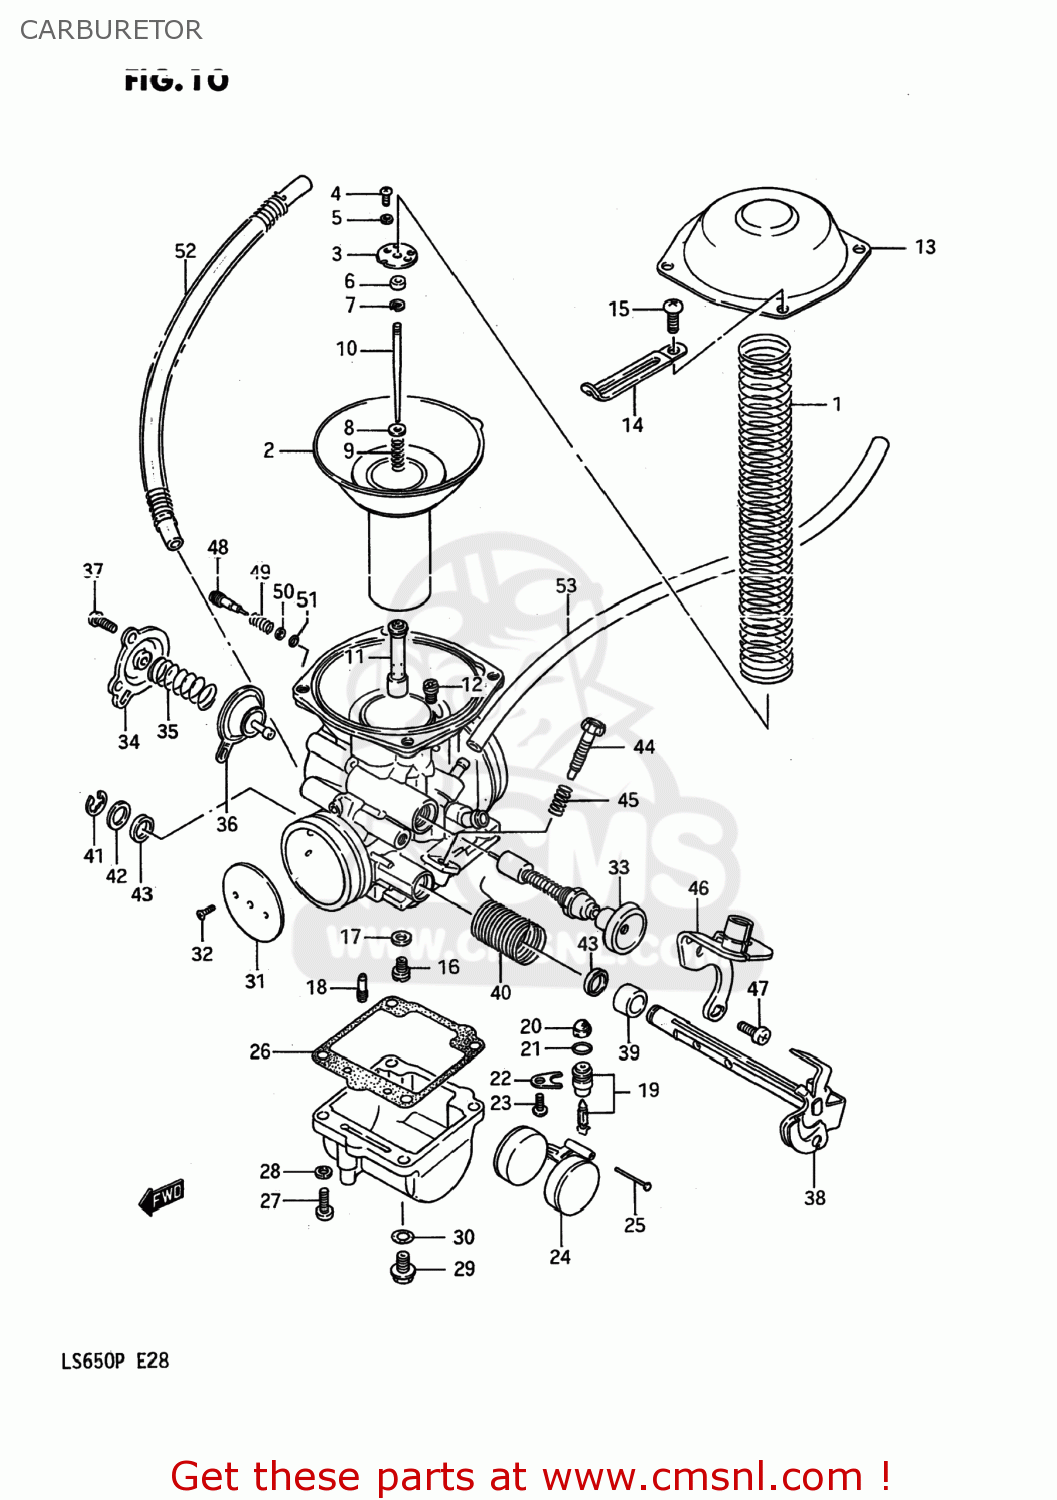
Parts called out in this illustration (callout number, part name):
1	SPRING
2	DIAPHRAGM ASSEMBLY
3	PLATE
4	SCREW
5	LOCK WASHER
6	RING
7	CLIP,NEEDLE
8	WASHER
9	SPRING
10	NEEDLE,JET
12	JET,PILOT AIR(70)
13	COVER
14	CLIP
15	SCREW 5X10
16	JET,MAIN(155)
17	WASHER,NEEDLE NOZZLE
18	JET,PILOT(47.5)
19	VALVE ASSEMBLY,NEEDLE
20	FILTER
21	O-RING,NEEDLE VALVE
22	PLATE
23	SCREW
24	FLOAT
25	PIN,FLOAT
26	GASKET,FLOAT CHAMBER (NAS)
27	SCREW
28	LOCK WASHER
29	PLUG,DRAIN
30	GASKET (NAS)
31	VALVE,THROTTLE (BUTTERFLY)
32	SCREW
33	PLUNGER ASSEMBLY
34	COVER
35	SPRING
36	DIAPHRAGM ASSY
37	SCREWM4X0.7X10
38	SHAFT ASSEMBLY,THROTTLE
39	RING
40	SPRING
41	E RING
42	GASKET,THROTTLE SHAFT (NAS)
43	SEAL
44	SCREW,THROTTLE STOP
45	SPRING
46	BRACKET ASSY
47	SCREW
48	SCREW,PILOT AIR
49	SPRING
50	WASHER
51	O RING,PILOT AIR SCREW
52	HOSE ASSEMBLY
53	HOSE
